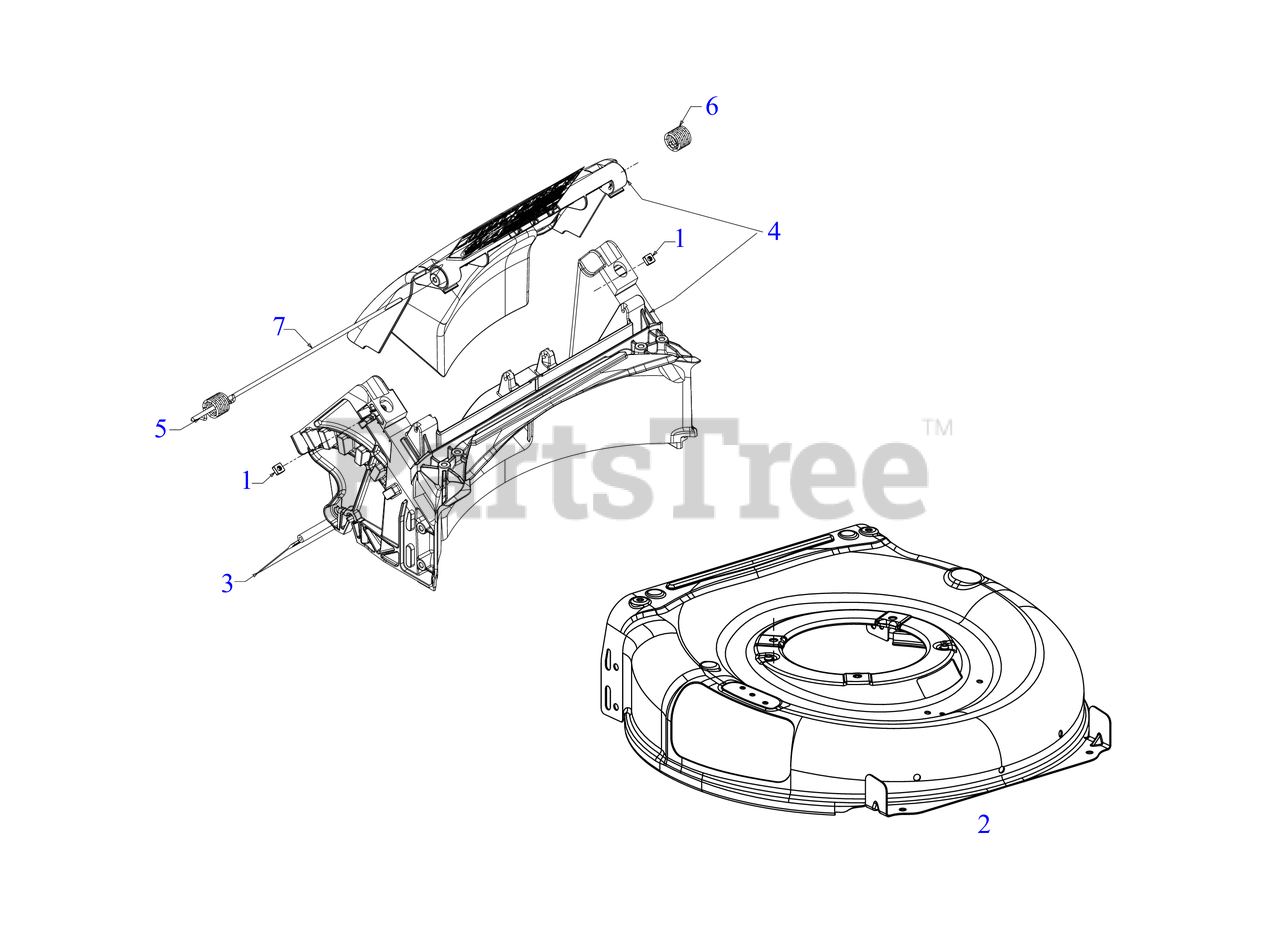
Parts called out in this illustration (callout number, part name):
1	SQUARE NUT 1/4-20
3	TRAILSHIELD
4	REAR BAG DOOR ASSEMBLY
5	TORSION SPRING (RH)
6	TORSION SPRING (LH)
7	REAR DOOR PIVOT ROD
